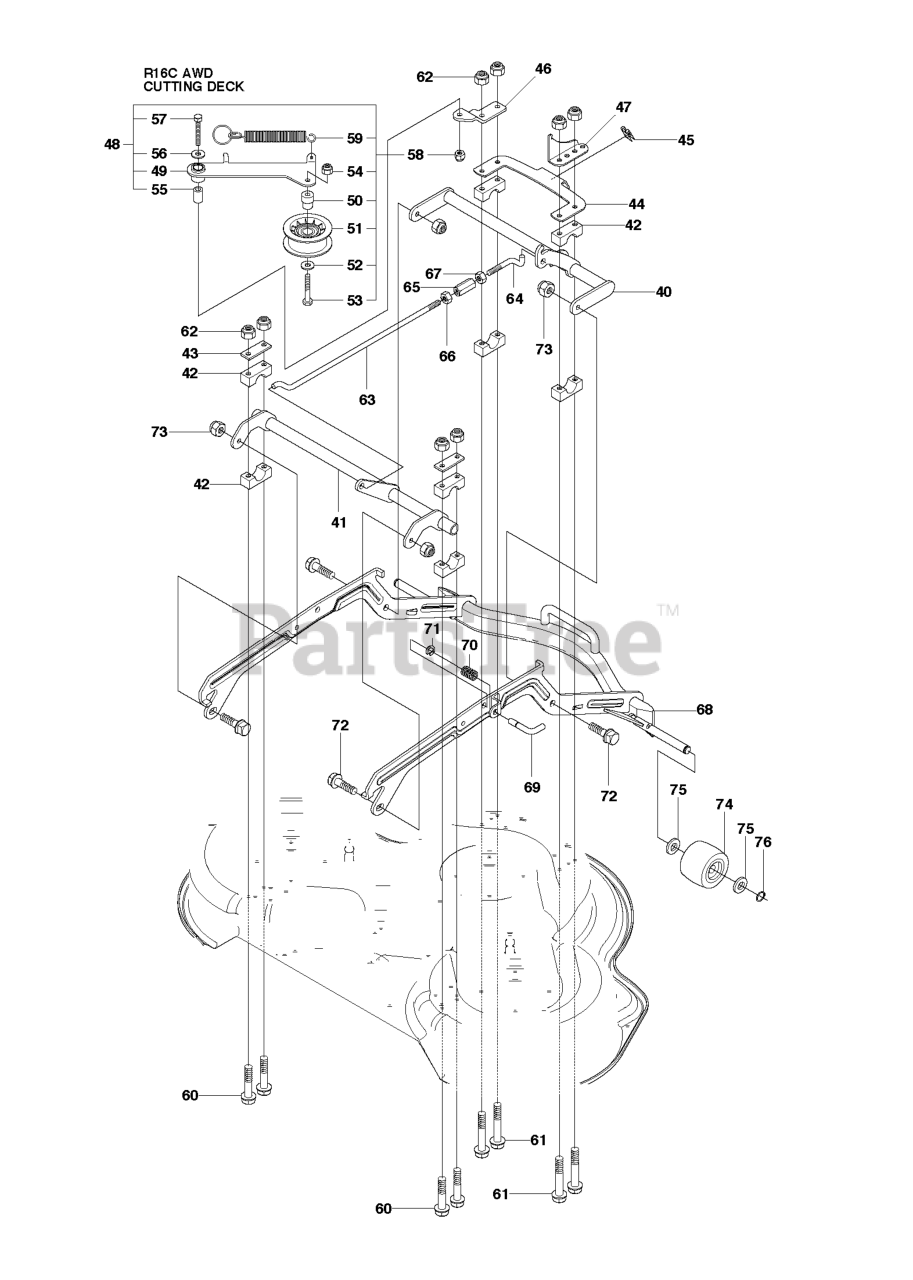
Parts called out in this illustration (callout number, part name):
51	PULLEY
54	LOCKNUT M8
57	SCREW
58	LOCKNUT M8
59	SPRING
62	LOCKNUT M8
67	NUT
73	LOCKNUT M8
74	DECK ROLLER, FRONT
76	RETAINING RING SGA 15
